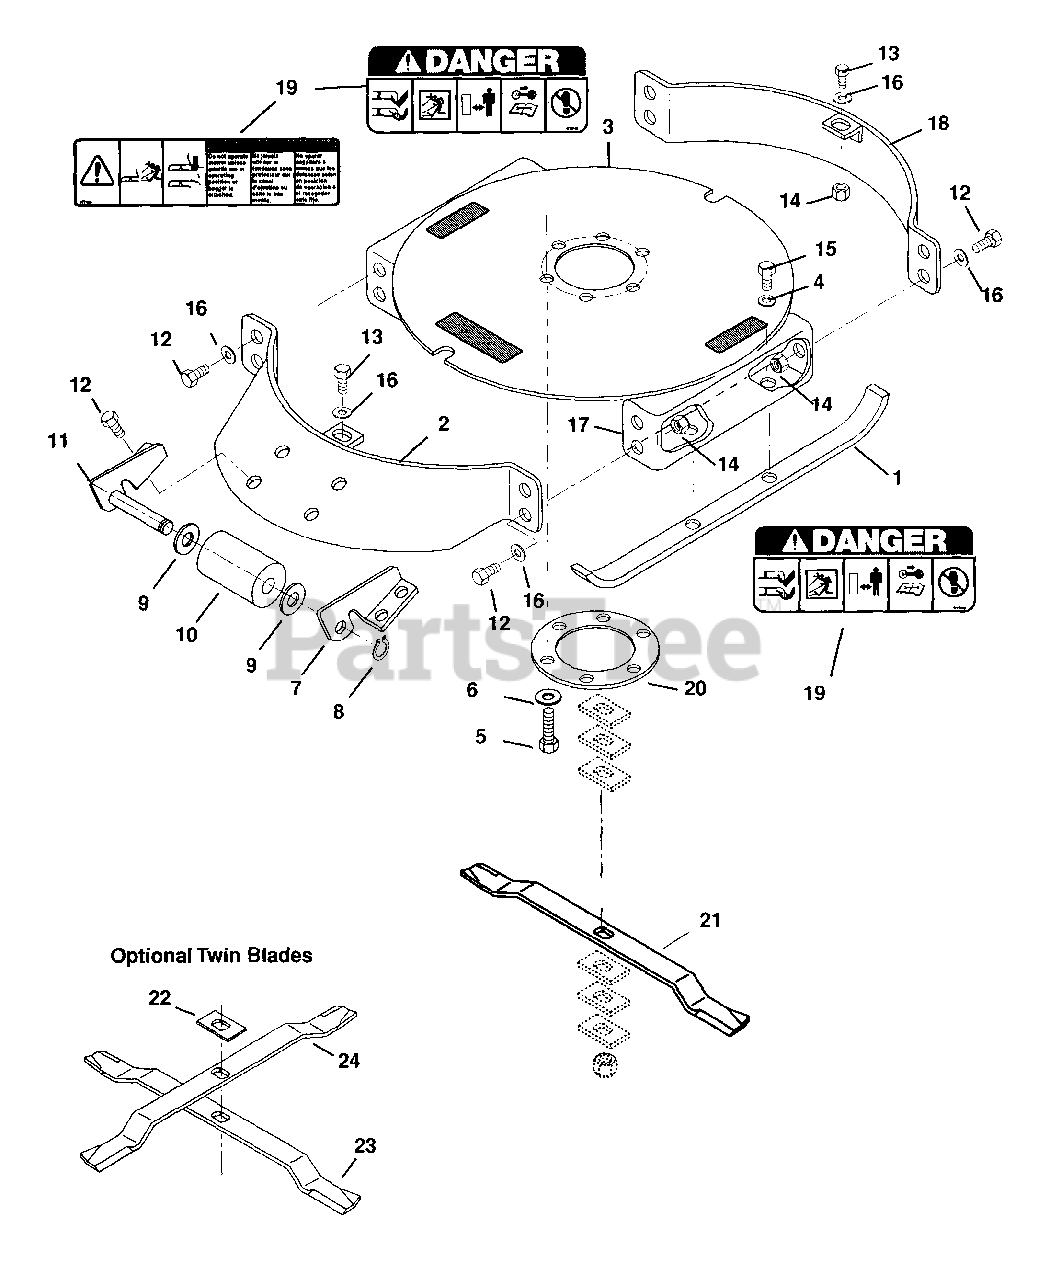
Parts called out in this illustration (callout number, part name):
1	Skid-Rotary Mower
2	Fender-Front 30" Mower
3	Deck-Weldment 30 in.
4	Washer-Lock .31
5	Bolt-Hex .50-13 x 1.75 Grade 5
6	Washer-Flat-Steel .563 x 1.38 x .109
7	Bracket-Wheel L-H
8	Ring-Retaining-External .625 x .042
9	Washer-Flat-Stainless Steel .656 x 1.25 x .1
10	Roller-Gage
11	Weldment-Bracket
12	Bolt-Hex .31-18 x .75 Grade 5
13	Bolt-Hex .31-18 x 8.75 Grade 5
14	Nut-Locking Nylon .31-18
15	Bolt-Hex .31-24 x .625
16	Washer, Flat .312 x .734 x .065
17	Panel Skid
18	Weldment-Rear Fender
19	Decal Set-Decks
20	Support Deck
21	Rotary Mower Blade .375"
22	Spacer-Cutting Height.125
23	Blade, 30" Mower-Thin
24	Blade, 30" Mower-Thin, Cross Slot
